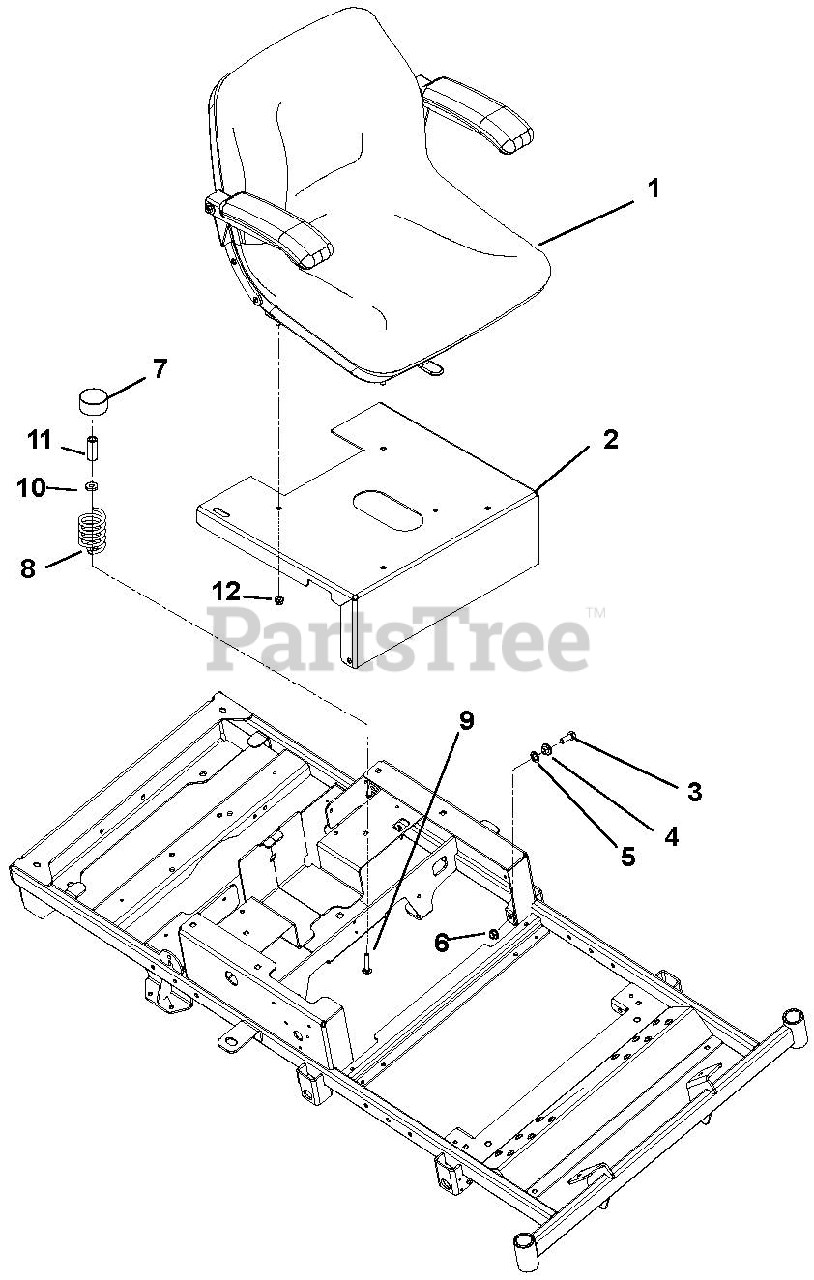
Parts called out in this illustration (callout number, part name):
1	SEAT, MILSCO XB-180
2	SEAT PLATE
3	@BLT-HEX .38-16X1.00 GR5 YWZC
4	BSHG-FLG .385X.500X.875X.406
5	WSHR-FL-STL .52X.827X.062 YWZC
6	@NUT-LK-NYL-FLG .38-16 YWZC
8	SPRING, SEAT
9	@BLT-RDHDSQNK .31-18X1.50 G5YZ
10	WSHR-FL-STL .328X.87X.179 YWZC
11	NUT, COUPLING 5/16-18 X 1 3/4
12	@NUT-LK-NYL-FLG .31-18 YWZC
